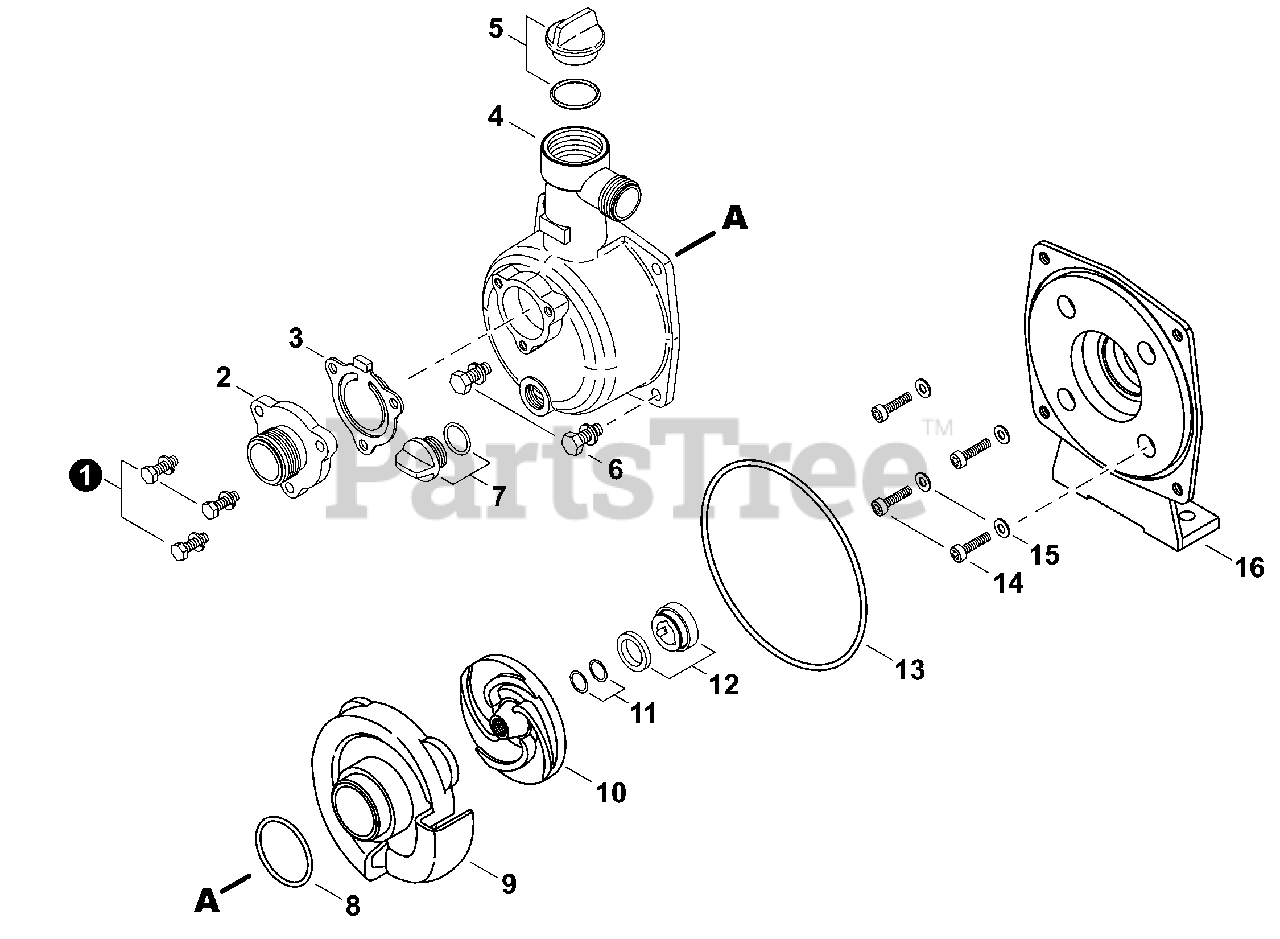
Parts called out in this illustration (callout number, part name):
1	BOLT M6×20
2	PORT, SUCTION
3	VALVE, SUCTION
4	CASE, PUMP
5	PLUG ASSY, FILLER
6	BOLT M8×20
7	PLUG ASSY, DRAIN
8	O-RING, VOLUTE
9	CASE, VOLUTE
10	IMPELLER
11	SHIM 0.3 MM THICK
12	SEAL, MECHANICAL
13	O-RING, PUMP CASE
14	BOLT M6×55
15	WASHER, SEALING Ø6
16	COVER, PUMP
